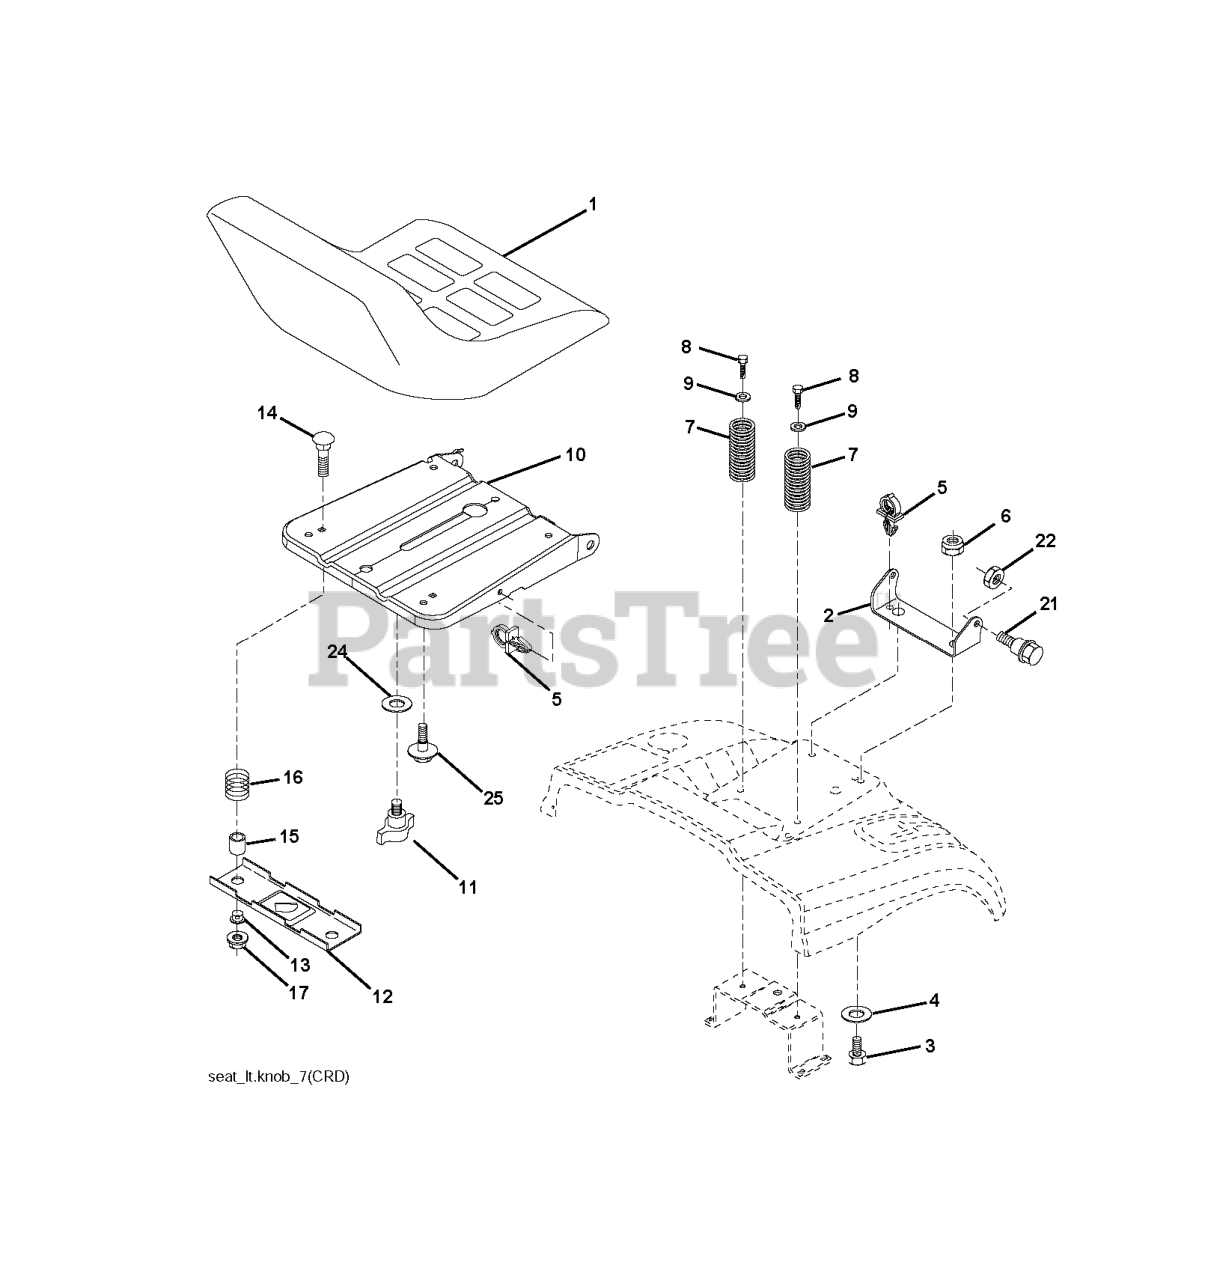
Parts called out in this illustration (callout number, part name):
1	RP SEAT
2	SEAT PIVOT BRKT
3	BOLT, HEX 3/8-16X1
6	NUT
7	SPRING COMPRESSION
8	SCREW 3/8-16X1
9	WASHER
10	PAN.ASM.SEAT.1SLOT
11	KNOB.SEAT.ADJ.WINGNUT
12	BRKT.MNTNG.SWITCH.SEAT.BLACK
14	BOLT.ROUND.HEAD.SQUARE.NECK
15	SPACER SPLIT 28X.96
17	NUT T
21	BOLT.SHOULDER.5/16-18
22	NUT.71038.31-18.HEX.NYLOCK
25	BOLT,SHOULD
